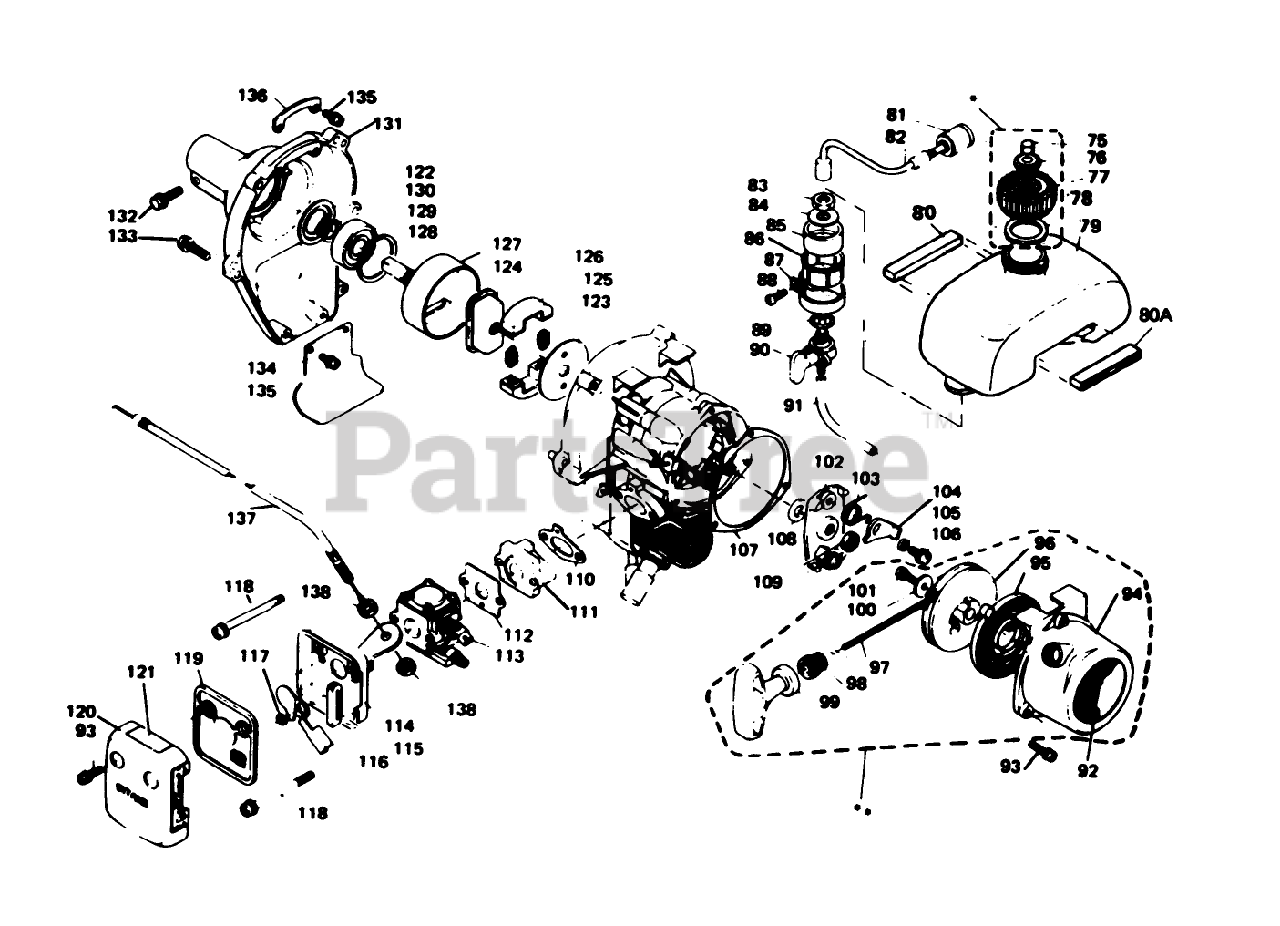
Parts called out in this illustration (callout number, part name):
75	Filter
76	Check Valve
77	Cap-Fuel Tank
78	Gasket-Fuel Tank Cap
79	Fuel Tank
80	Cushion
80A	Cushion
81	Fuel Strainer
82	Fuel Pipe
84	WASHER
86	COLLAR
87	CLAMP
88	SCREW
89	GASKET
90	FUEL VALVE ASM
91	FUEL PIPE
92	Decal
93	SCREW
94	Starter Case
95	REWIND SPRING
96	RECOIL DRUM
97	Rope-Starter
98	Rope Guide
99	Starter Handle
100	Washer
101	Screw
102	PAWL CATCHER
103	Ratchet Spring
104	RATCHET
105	RATCHET SPACER
106	SCREW
107	STARTER CASE GASKET
108	Spacer
109	Nut L.H.
110	GASKET
111	Insulator
112	GASKET
113	Carburetor Assy.
114	Case Air Cleaner
115	GROMMET
116	Choke Shutter
117	CHOKE SHUTTER SPACER
118	SCREW
119	AIR FILTER
120	AIR CLEANER COVER
121	Decal, Fuel Valve
122	Stopper
123	Side Plate, Clutch
124	Clutch Boss
125	Clutch Spring
126	CLUTCH SHOE
127	Clutch Drum
128	Circlip
129	Ball Bearing
130	Circlip
131	Fan Cover
133	Screw
134	Bracket
135	SCREW
137	Throttle Cable
